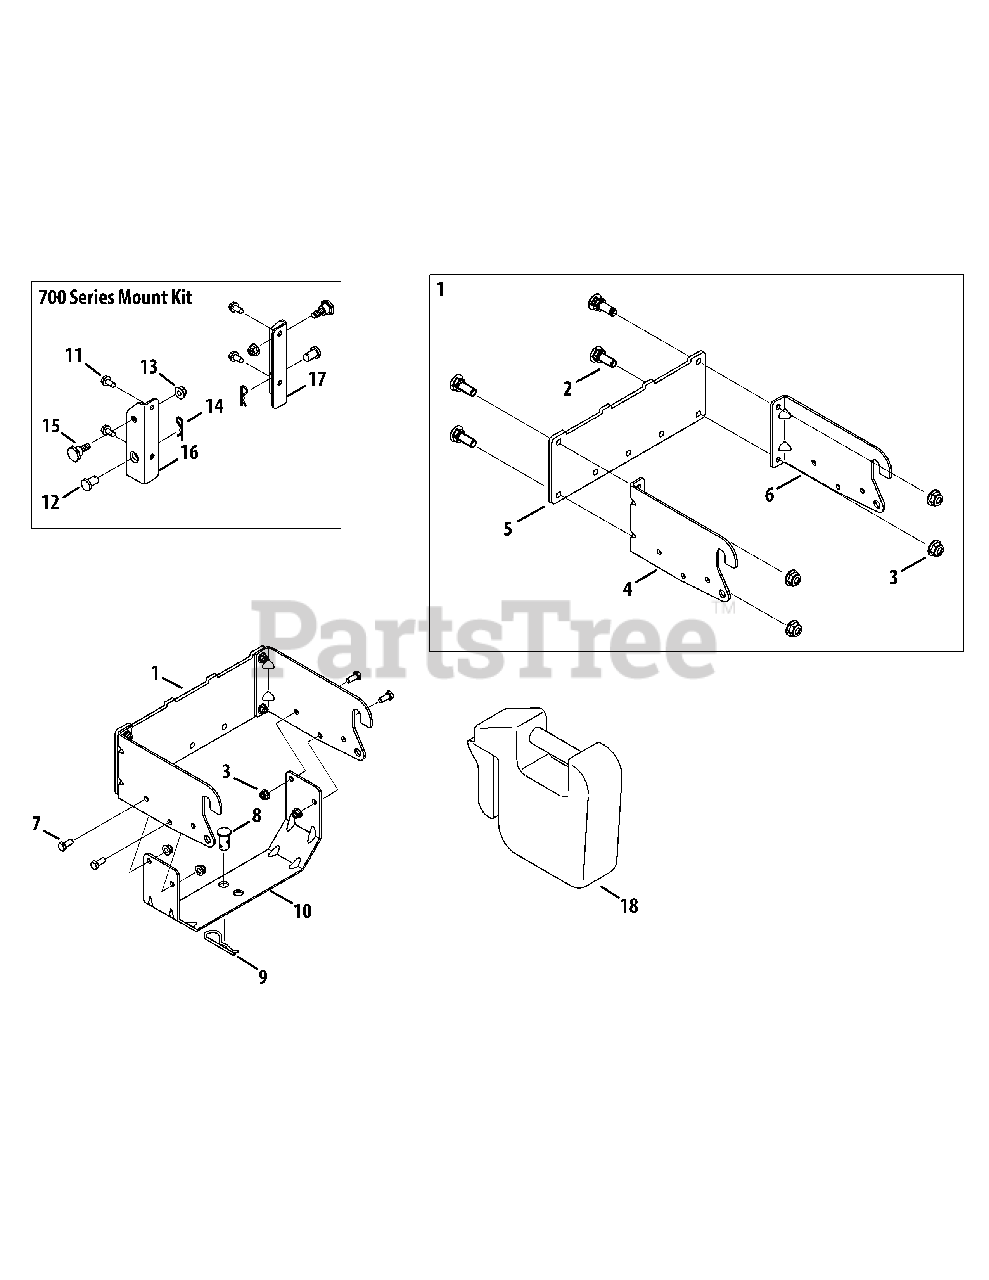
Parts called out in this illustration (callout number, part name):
1	Hitch Bracket Assembly
2	Carriage Screw, 5/16-18 x 1.00"
3	Flange Lock Nut, 5/16-18
4	Hitch Bracket, RH
5	Rear Attachment Bracket
6	Hitch Bracket, LH
7	Hex Head Screw, 5/16-18 x .75"
8	Clevis Pin, .62" Dia.
9	Internal Cotter Pin, .148 x 3.00
10	Universal Bracket Support
11	Tap Screw, 5/16-18 x .750
12	Clevis Pin, .50 x .78 Lg.
13	Flange Lock Nut, 3/8-16
14	Click Pin, .092 x 1.64 Lg.
15	Shoulder Screw, .625 x .412
16	Mounting Bracket, RH
17	Mounting Bracket, LH
18	Suitcase Weight, 45 lb.
18	Suitcase Weight, 42 lb. (plastic)
